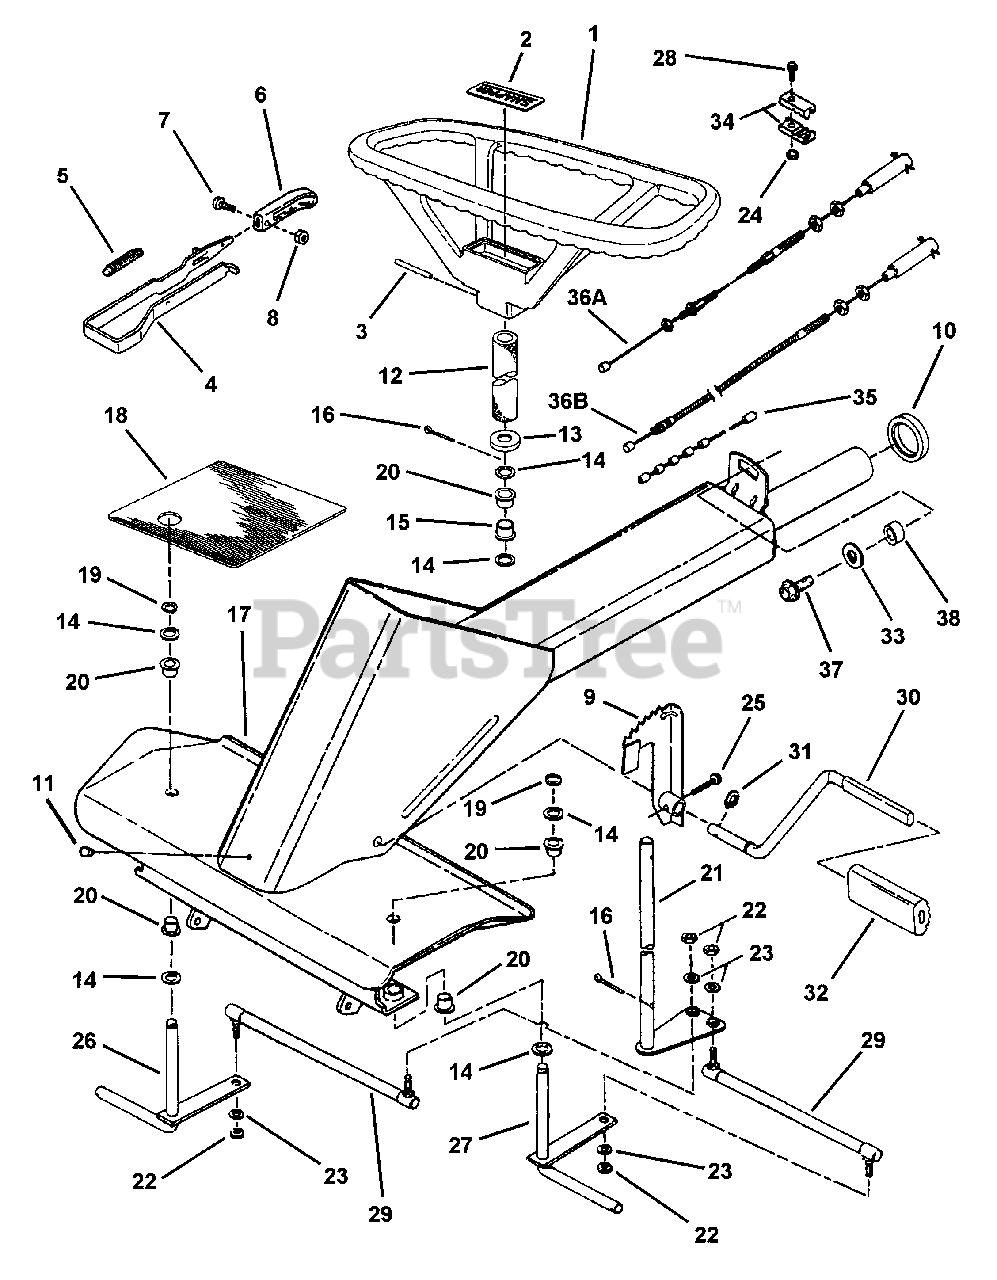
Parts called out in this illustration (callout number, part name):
1	ASSEMBLY, Steering Wheel
2	DECAL, Snapper
3	PIN, 1/4 x 1-1/2" Roll
4	LEVER, Clutch/Brake
5	SPRING
6	KNOB
7	SCREW, #8-32 x 3/8" Cross Recess
8	NUT, #8-32 Hex, Grade 2B
9	ARM, Clutch/Brake
10	SPACER, Main Tube
11	PLUG
12	COVER, Steering Shaft (Foam)
13	COVER
14	WASHER, 3/4 Flat
15	BUSHING, 3/4" Steering Shaft
16	COTTER-PIN, 3/16 x 1-1/2"
17	FRAME, Front (42" Models)
18	PAD, Foot
19	RING, 5/8" External Retaining
20	BEARING
21	SHAFT, Steering (Wide Front End)
22	NUT, 5/16-24 Hex, Grade 5
23	WASHER, 5/16 Split Lock
24	NUT, 1/4-20 Hex Center Lock, Grade 5 or B
25	SCREW, 5/16-18 x l-1/4" Hex Washer Head, Self-Tap
26	PIN, Wide King (Right Side)
27	PIN, Wide King (Left Side)
28	SCREW, 1/4-20 x 3/4" Hex Head Cap, Grade 5
29	TIE-ROD
30	PEDAL, Clutch/Brake
31	RING, 5/8" External Retaining
32	PAD, Clutch/Brake Pedal
33	WASHER, 3/8" Flat
34	UNION, Cable
35	CABLE, Clutch
36A	CABLE, Brake
36B	CABLE, Brake, Snap-in
37	SCREW, 3/8-16 x 5/8" Hex Washer Head, Self-Tap
38	SPACER, 25/64 x 5/8 x 3/16"
